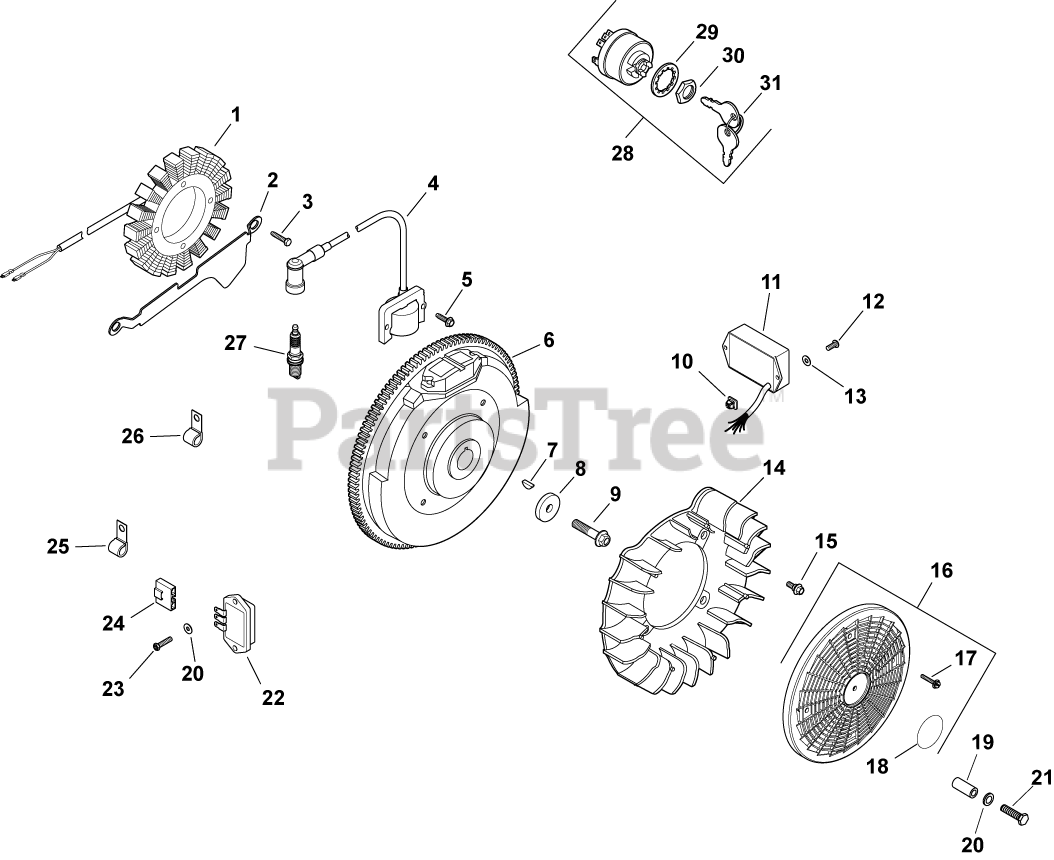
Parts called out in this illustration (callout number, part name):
1	KIT, 15 / 20 AMP STATOR
2	BRACKET, STATOR WIRE
3	SCREW, M5X0.8X25 - (#25086402S)
4	MODULE, IGNITION
5	SCREW, SKT THD FRM M5X0.8X25
6	FLYWHEEL, PAINTED-USE 24 025 57-S
7	KEY, 3/16" X 5/8"
8	WASHER, FLAT 13/32"
9	SCREW, FLG M10X1.5X45 - (#25086361S)
10	NUT, PLASTIC
11	MODULE, SPEED ADVANCE-DISCONTINUED SEE PB265
12	SCREW, PHL HD #11-16X1/2"
13	WASHER, FLAT 1/4" (O.D. 1/2")
14	FAN (WITH HOLE)-USE 24 157 16-S
15	BOLT, SHOULDER
16	KIT, GRASS SCREEN
17	SCREW, WSH HD TAP #8-18X1/2"
18	DECAL, GRASS SCREEN USE 24 113 499-S
19	SPACER - DISCONTINUED
20	WASHER, FLAT 3/16"
21	SCREW, SLT HD CAP M4X0.7X25
22	REG/RECT-15 AMP (KM)-USE 41 403 10-S
23	SCREW, PHL HD #11-16X7/8"
24	CONNECTOR, BODY (KM)-USE 25 155 41-S
25	CLIP, CABLE
26	CLIP, CABLE - USE 24 154 10-S
27	PLUG, SPARK (STD)
28	SWITCH ASSY, KEY (KM)-USE 25 099 32-S
29	WASHER, INTERNAL TOOTH
30	NUT, KEY SWITCH
31	KEY, SET -USE 48 340 01-S
